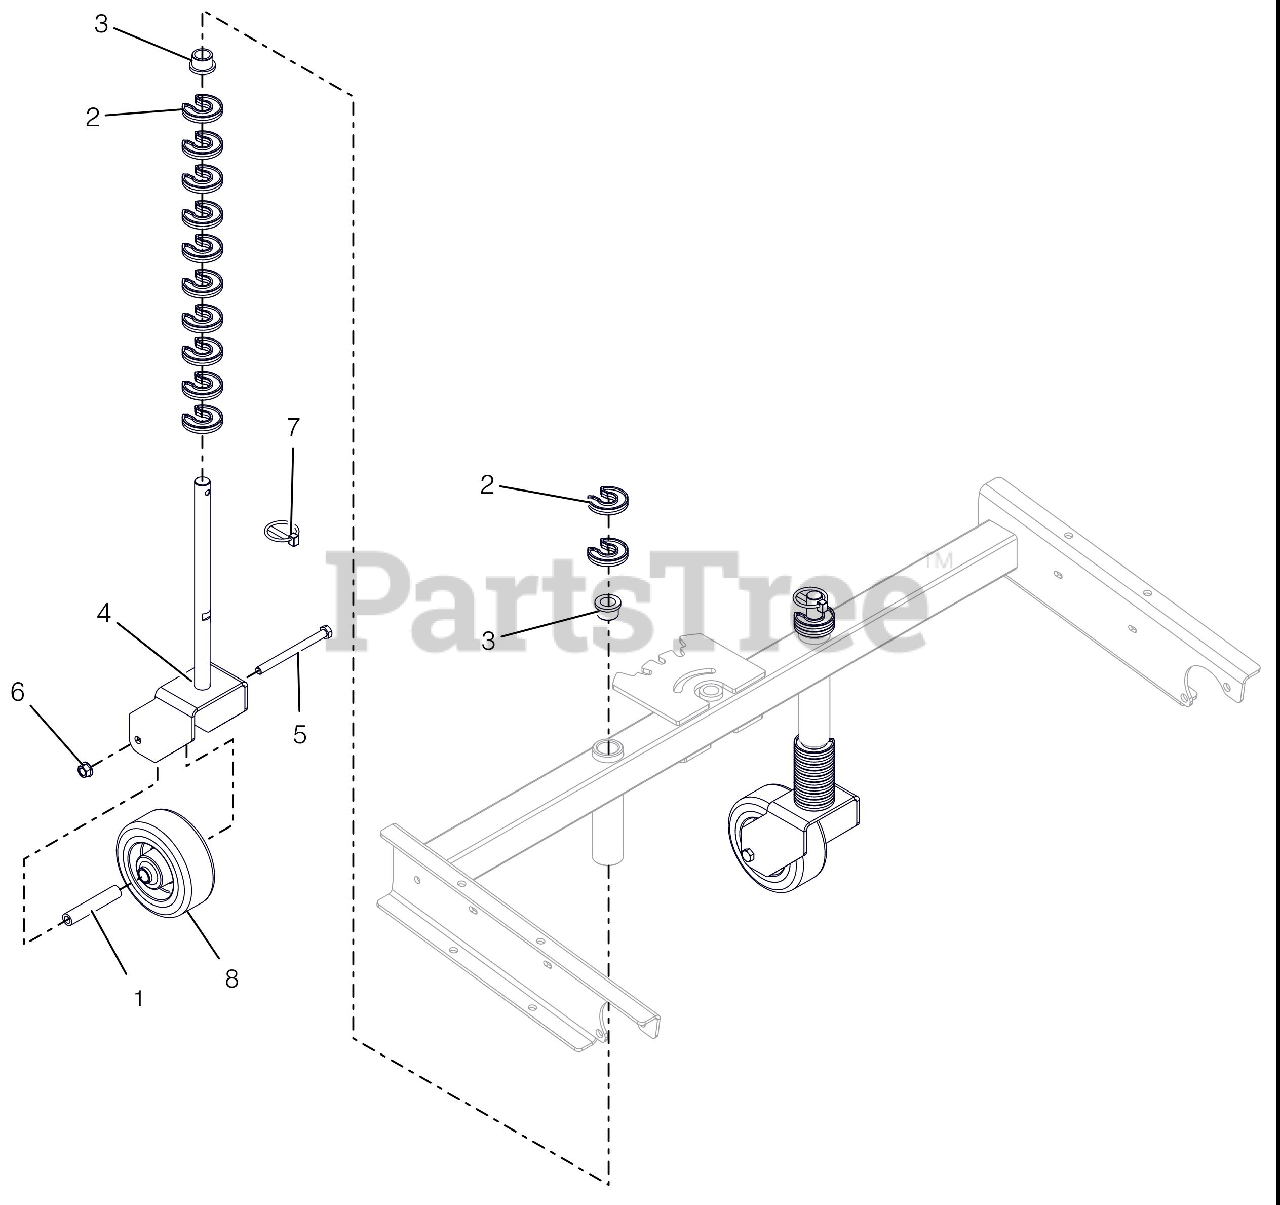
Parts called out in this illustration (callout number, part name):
1	SPACER, CASTER WHEEL
2	CLIP-HOC FIXED
3	BUSHING, FLANGE .75X.75X1.0
4	FORK, CASTER
5	@BLT-HEX .38-16X4.50 GR5 YWZC
6	@NUT-LK-TOP-FLG .38-16 YWZC
7	PIN, 1/4X1-9/16 LYNCH
8	WHEEL, CASTER - 5"OD
